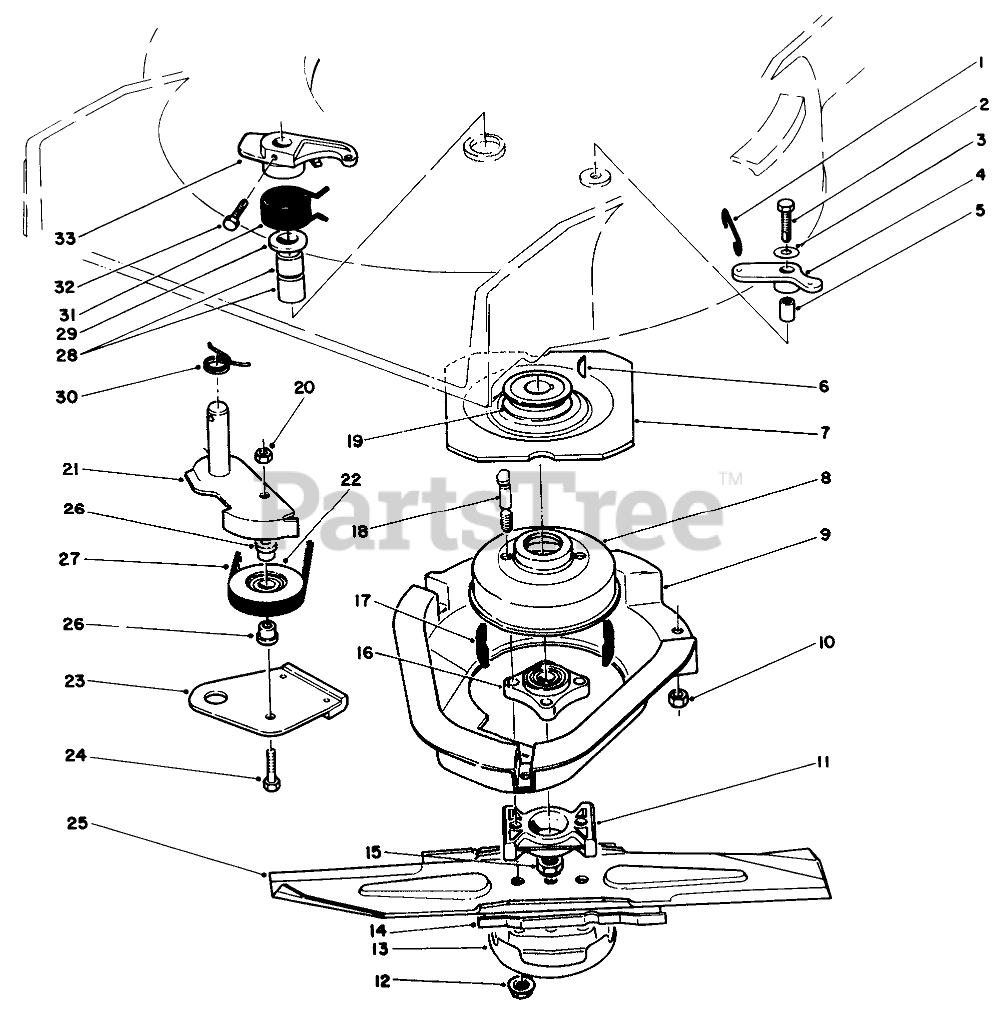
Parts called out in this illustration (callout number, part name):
1	LINK-CONTROL
2	SCREW-HH
3	WASHER-PLAIN
4	BELLCRANK
5	SLEEVE-BELLCRANK
6	KEY-WOODRUFF
7	Flywheel
8	Drum-Brake
9	Shield
10	NUT-LOCK, NI
11	SPACER-BLADE
12	NUT-LOCK
13	CUP-SCALP, ANTI
14	Accelerator
15	NUT-LOCK, NI
16	HUB ASM
17	DAMPENER-VIBRATION
18	BOLT-BLADE
19	PULLEY-DRIVER
20	NUT-LOCK, NI
21	ARM-IDLER
22	PULLEY-IDLER
23	BRAKE PLATE ASM
24	SCREW-HH
25	Blade
26	SPACER-PULLEY, IDLER
27	V-BELT
28	BEARING
29	WASHER
30	SPRING-TORSION
31	SPRING-TORSION
32	SCREW-HH
33	LEVER
